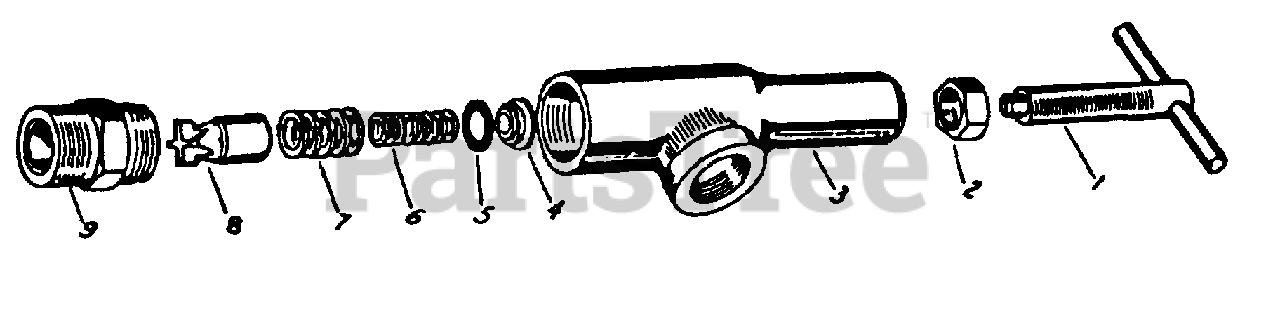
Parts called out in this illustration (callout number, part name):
1	Adj. Screw Assy. 5896 Brass
2	Locknut 5898 Brass
3	Body 68 18-1/2 Brass
4	Spring Retainer 6545 Brass
5	Gasket 5899-BU Buna N
6	Inside Spring 6547-SS
7	Outside Spring 6546-SS
8	Guide Seat 9897 Brass
9	Inlet Adapter 6789 Brass
